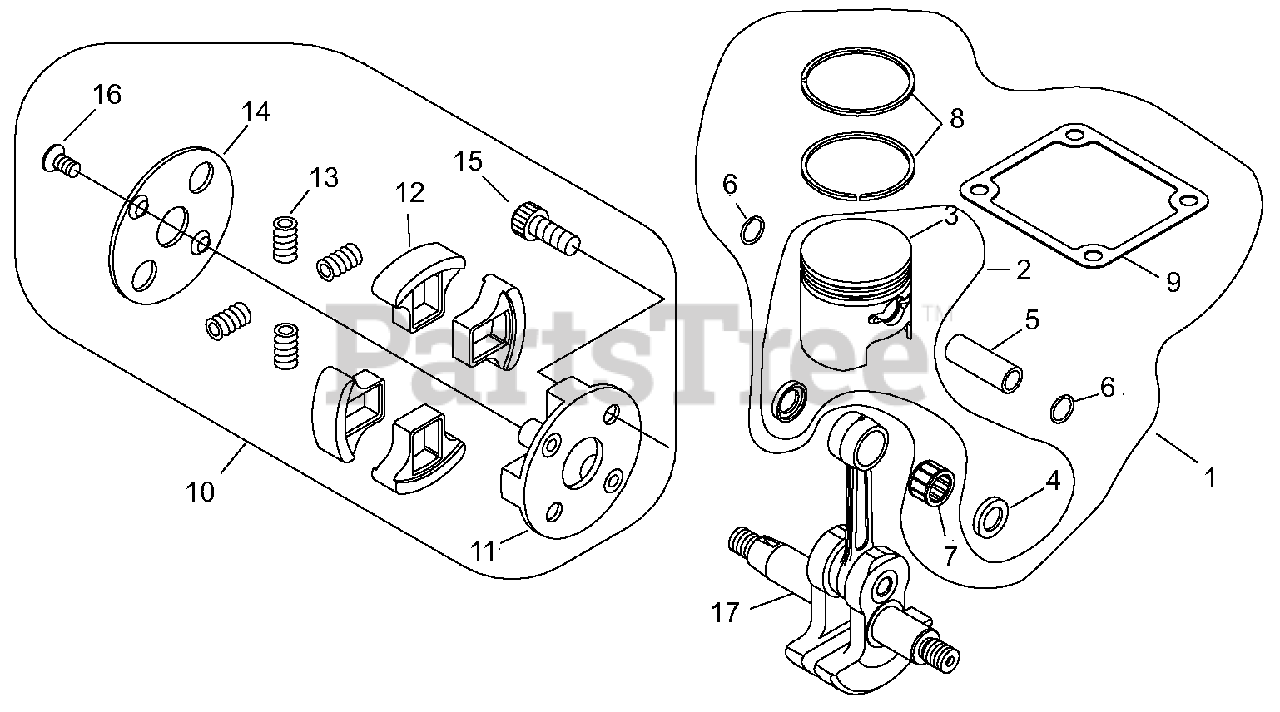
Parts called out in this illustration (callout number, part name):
1	PISTON KIT
2	PISTON SET
3	PISTON
4	WASHER, THRUST 11
5	PIN, PISTON
6	RING, SNAP
7	BEARING, NEEDLE 11
8	RING, PISTON
9	GASKET, CYLINDER
10	CLUTCH ASSY
11	BOSS, CLUTCH
12	SHOE, CLUTCH
13	SPRING, CLUTCH
14	PLATE, CLUTCH
15	BOLT, CLUTCH
16	BOLT 5
17	CRANKSHAFT ASSY
